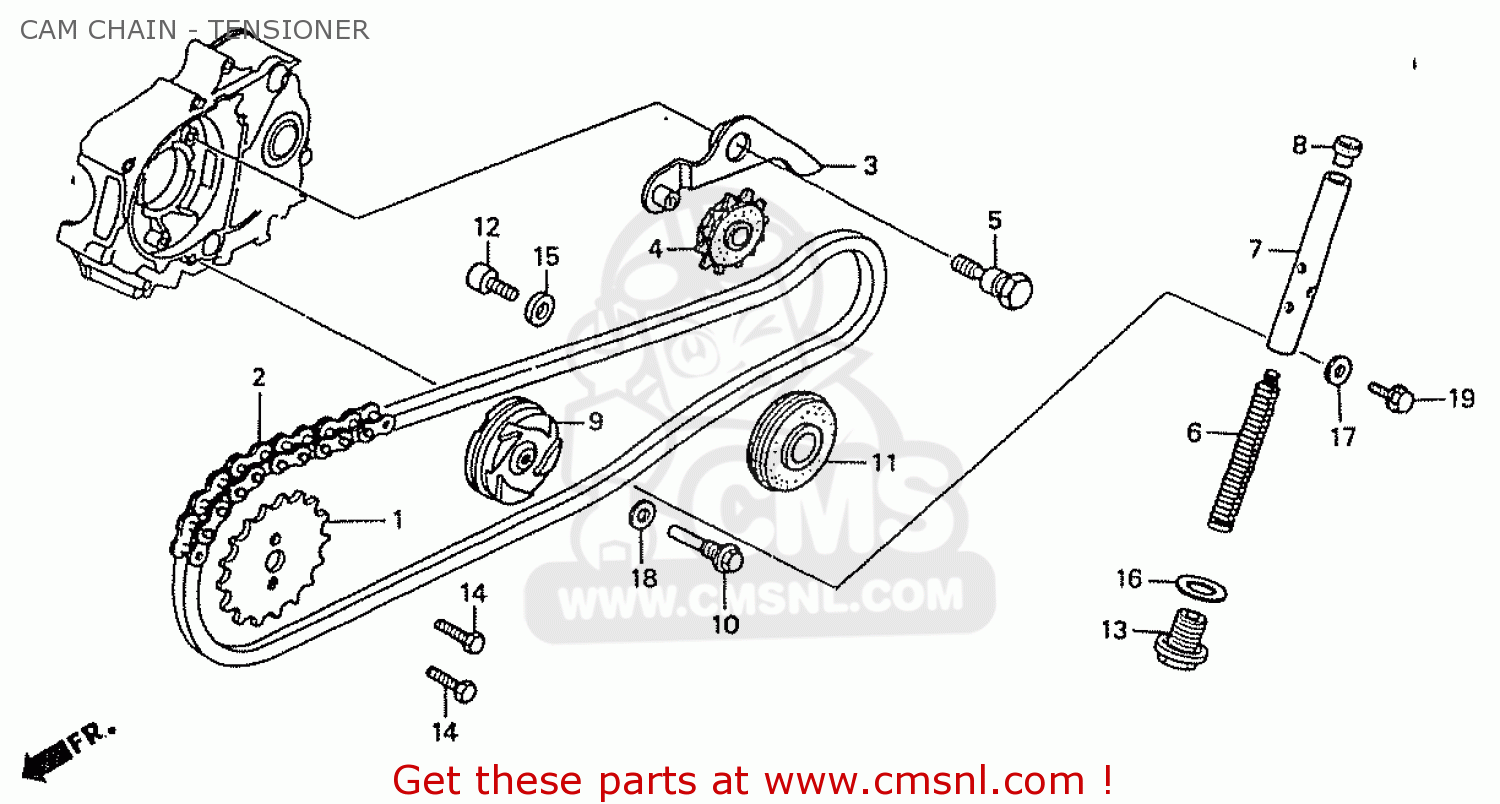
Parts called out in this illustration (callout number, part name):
1	SPROCKET,CAM
2	CHAIN,CAM
3	ARM,CHAIN TENSION
4	ROLLER,CAM CHAIN
5	PIVOT, TENSIONER
6	SPRING,CAM CHAIN
7	ROD COMP.,CAM CHA
8	HEAD,TENSIONER
9	ROLLER COMP,CAM C
10	PIN,GUIDE ROLLER
11	ROLLER COMP,CAM C
12	BOLT,CAM CHAIN GU
13	BOLT, SEAL, 14
14	BOLT KNOCK 5MM
15	WASHER,PLAIN 6.5X
16	WASHER, SEALING
17	WASHER, 12MM
18	WASHER,8MM
19	BOLT FLANGE 6X18
